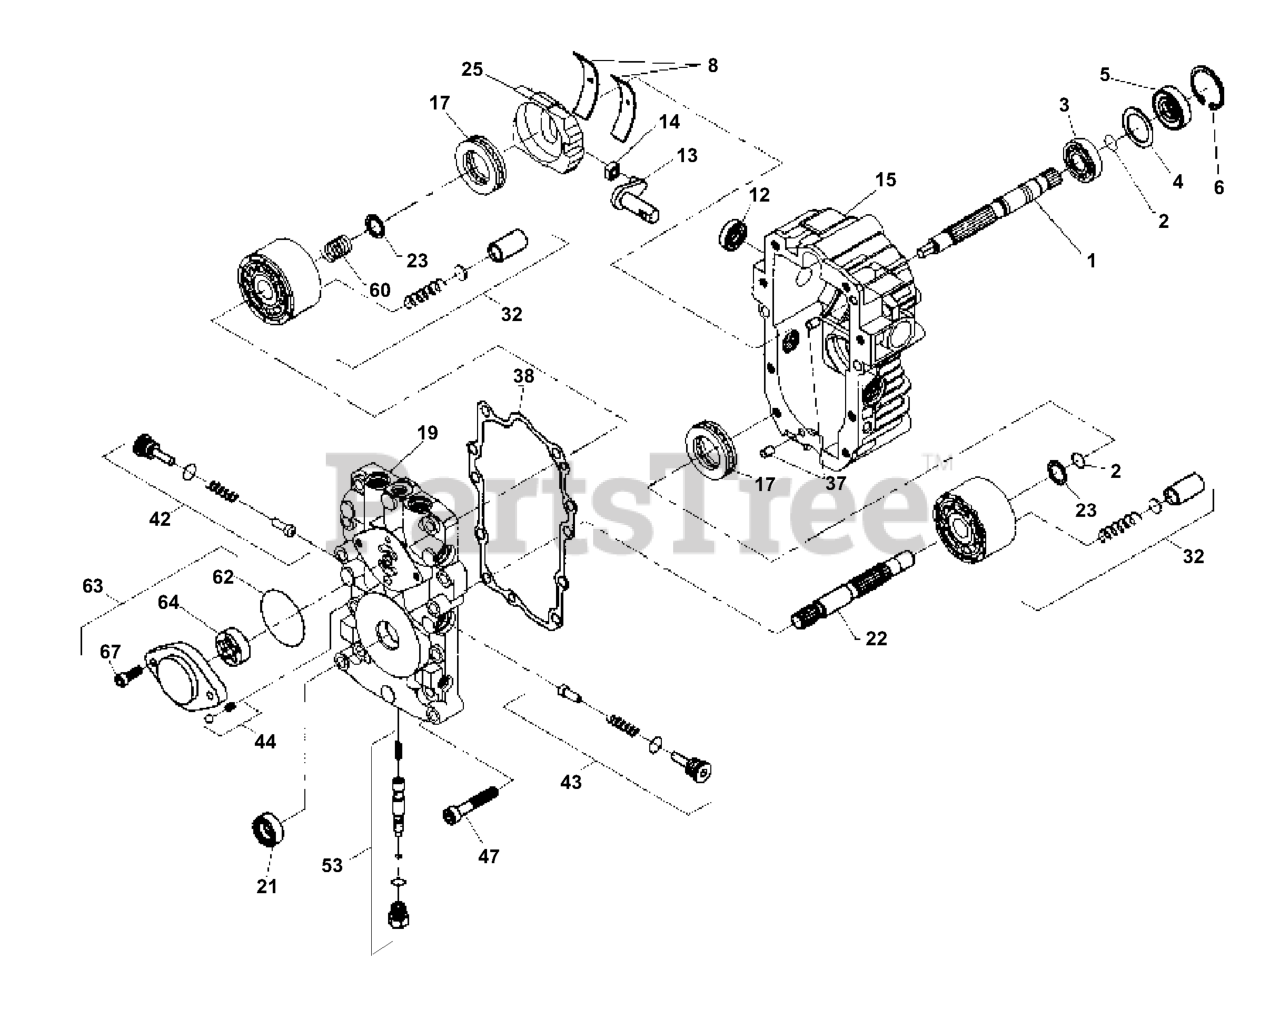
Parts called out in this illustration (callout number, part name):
1	SHAFT, PUMP
2	RETAINIANG RING
3	BALL BEARING 2003043
5	SEAL LIP
6	RETAINING PIN
8	CRADLE BEARING
13	TRUNION ARM
14	GUIDE 2000015 HYD
15	HOUSING KIT, TRANSMISSION
17	BALL BEARING
19	CENTER SECTION KIT
21	LIP SEAL 9008000-0127
22	SHAFT MOTOR 2003034
23	Washer, Block Thrust
25	SWASHPLATE,VARIAB
32	Block Assembly
38	GASKET 2003060
42	CHECK VALVE KIT 2510050
43	CHECK VALVE KIT 2510050
44	CHARGE RELIEF KIT 2510011
53	KIT,BYPASS VALVE(2513011)
60	Block Spring
62	O-RING.HYDRO GEAR.9004101-1340
63	CHARGE PUMP KIT
64	GEROTOR ASSEMBLY
67	SCREW, SOCKET HEAD CAP
